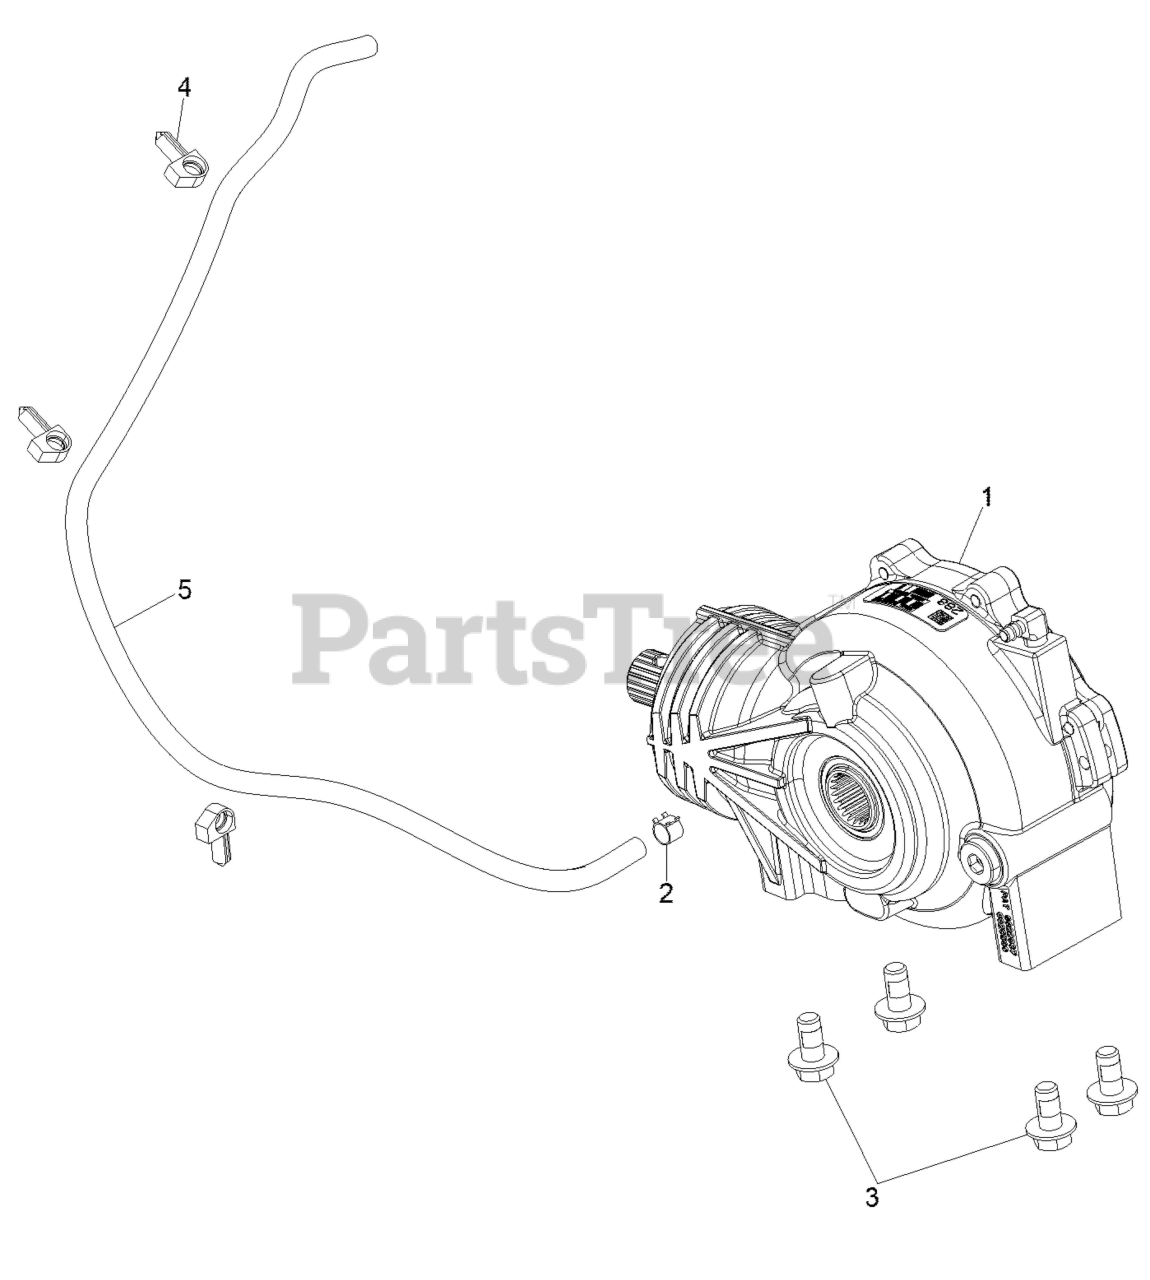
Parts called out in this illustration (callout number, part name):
1	ASM., GEARCASE, FRONT
2	CLAMP,HOSE(10)
3	BOLT-M10X1.5X20,HXFLG,W/PATCH
4	CLIP,ROUTING,.472 B.D.,HINGED
5	LINE-BOOST,3/16 ID,76CM
